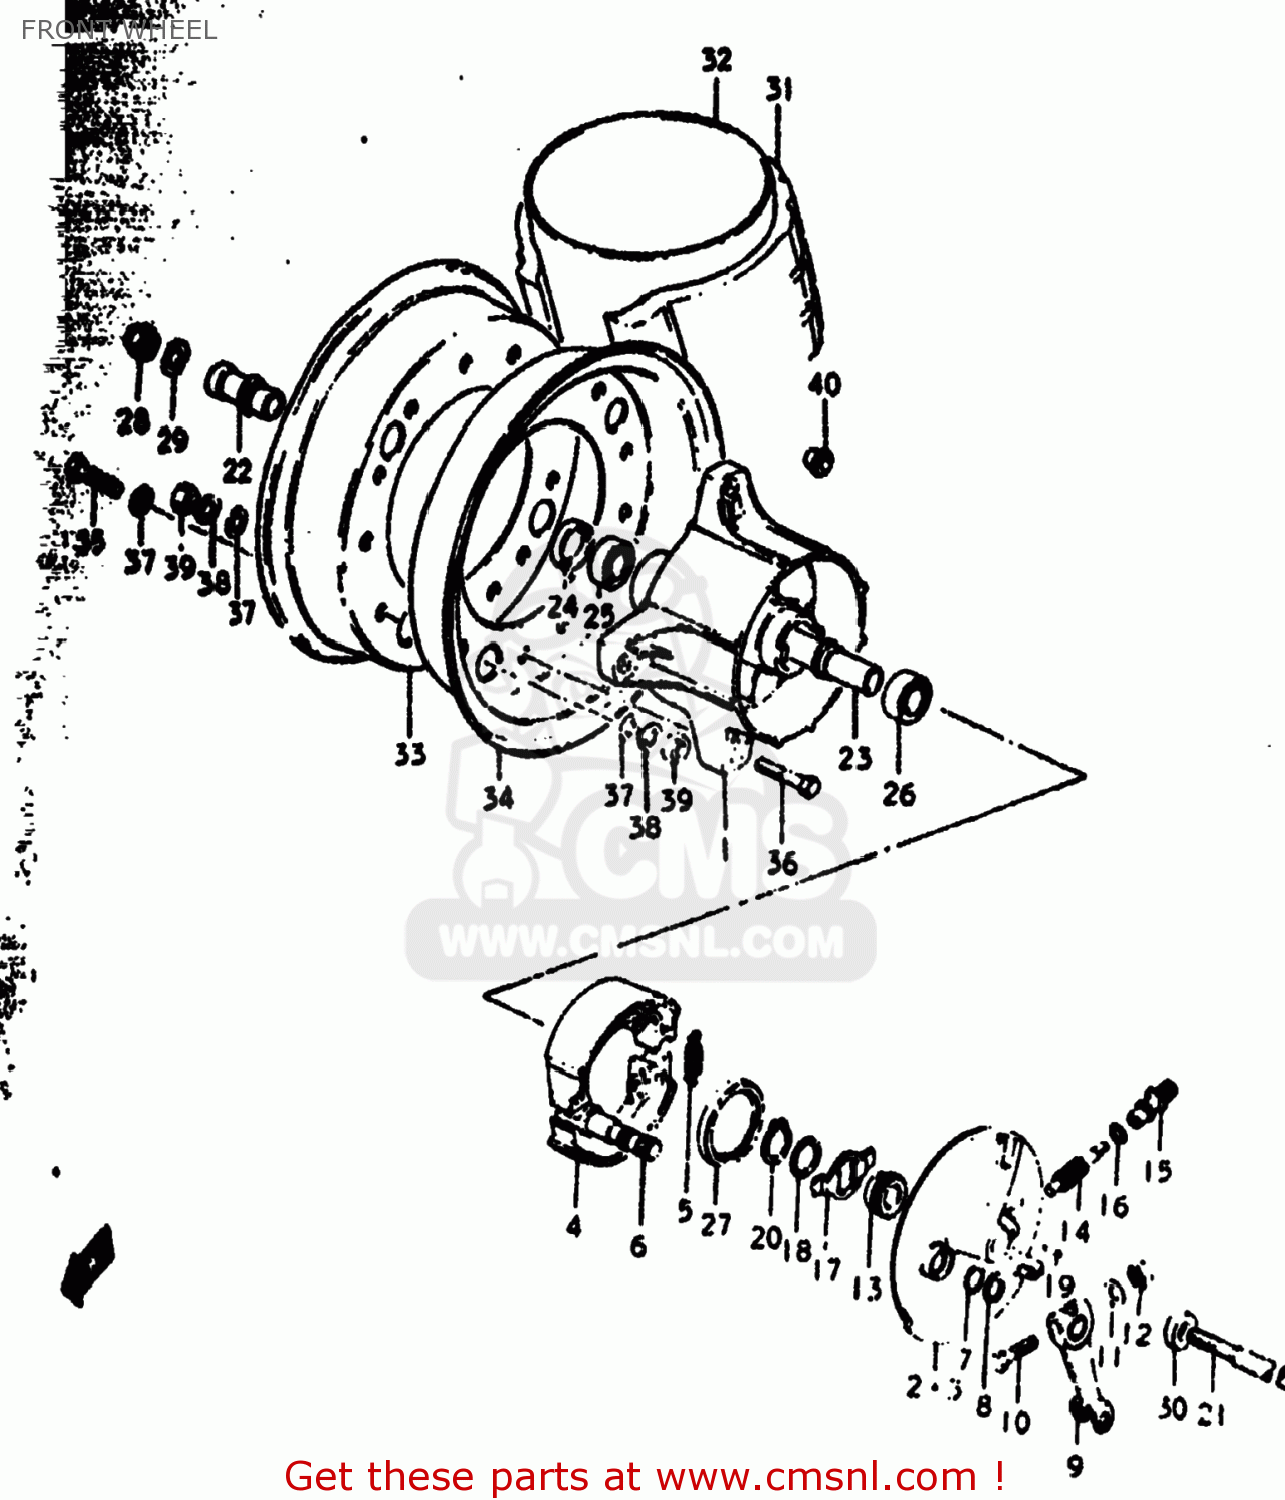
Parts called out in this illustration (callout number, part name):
1	DRUM,FRONT HUB
2	PANEL,FRONT HUB
3	PANEL,FRONT HUB
4	SHOE,BRAKE
5	SPRING(L:34)
6	CAM,FR BRAKE
7	O RING(D:2.5,ID:11.4)
8	WASHER(12.5X20X1)
9	LEVER,FR BRAKE CAM
10	BOLT
11	WASHER
12	NUT
13	GEAR,SPEEDOMETER
14	PINION,SPEEDOMETER
15	BUSH,METER GEAR OUTER
16	WASHER (5.1X9X0.4)
17	DRIVER,SPEEDOMETER GEAR
18	WASHER(18.5X24X1)
19	SCREW
20	CIRCLIP
21	AXLE,FRONT
22	SPACER,FRONT AXLE,RIGHT
23	SPACER,FRONT HUB BEARING
24	OIL SEAL K,L,M,A,B
25	BEARING
26	BEARING, LH
27	OIL SEAL (43X58X7)
28	NUT
29	WASHER K,L,M,A
30	WASHER
31	TIRE. (BRIDGESTONE)
32	TUBE,INNER
33	RIM,WHEEL,RIGHT
34	RIM,WHEEL,OUTER
35	BOLT
36	BOLT
37	WASHER
38	LOCK WASHER
39	NUT
40	BUSHING
